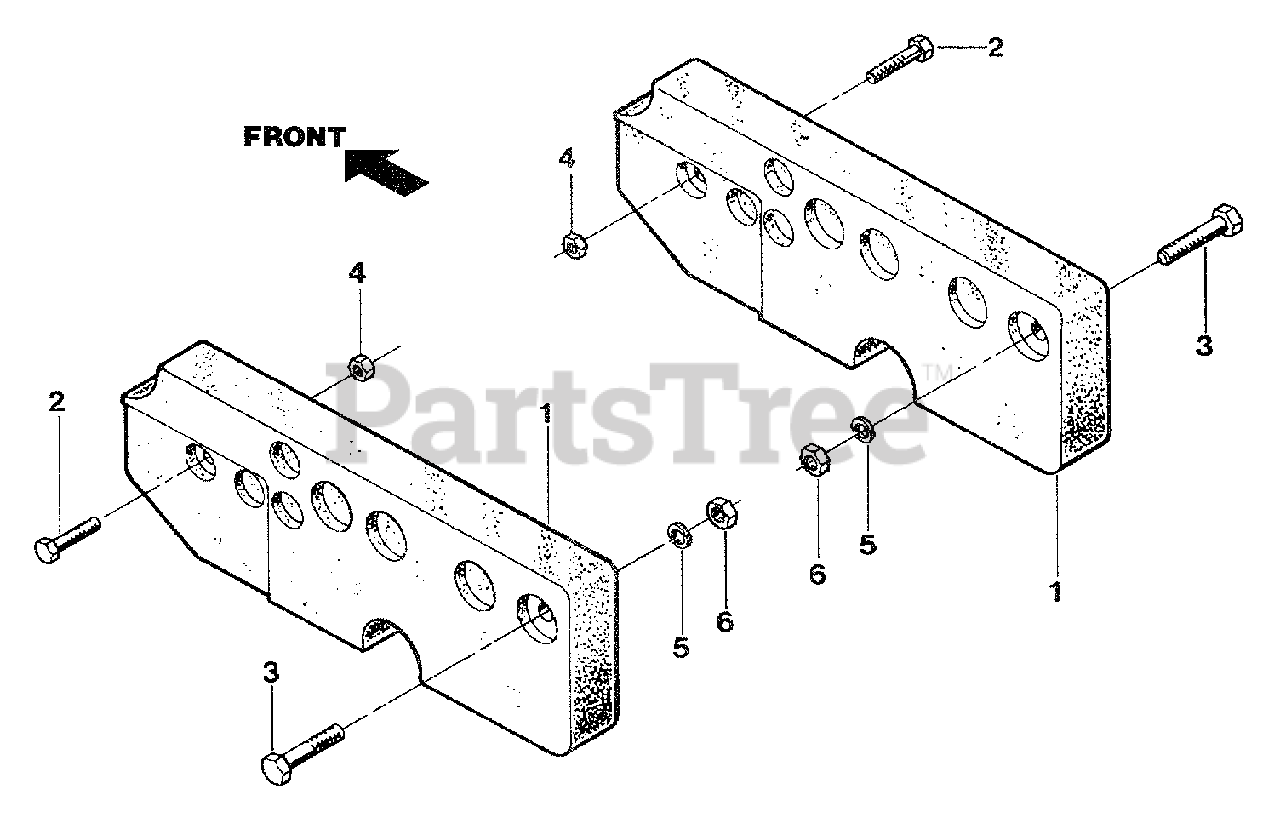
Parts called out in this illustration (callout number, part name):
1	Frame Weight
2	Bolt-Hex Head, 1/4-20 x 1-114
3	Bolt-Hex Head, 5/16-18 x 1-1/2
4	Nut, Hex Hd., 1/4-20
5	Lockwasher-5/16
6	Nut, Hex Hd., 5/16-18
